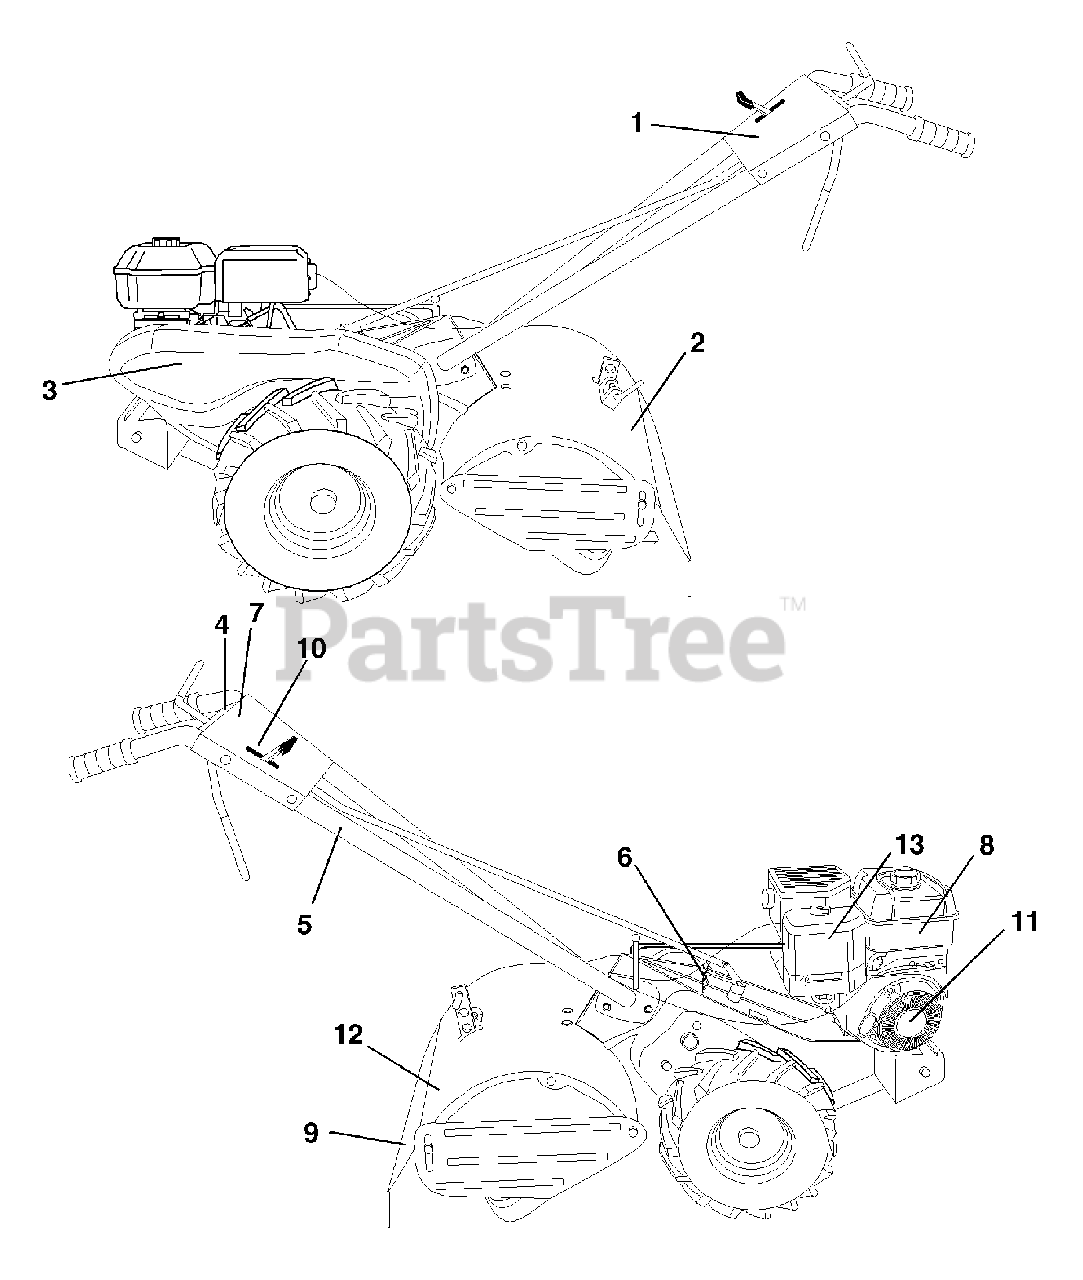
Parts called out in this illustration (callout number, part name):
1	Decal, Logo
2	Decal, Logo
3	Decal, Logo
4	Decal, Instruction, Tilling
5	Decal, Hand Placement
6	Decal, Shift Indicator
7	Decal, Pnl Cntrl Reverse
8	Decal, OHV.N-I/C
9	Decal, Warning, Rotating Tines
10	Decal, Throttle
11	Decal, Rewind Intek
12	Decal, Warning Till
13	Decal, B&S Tiller
